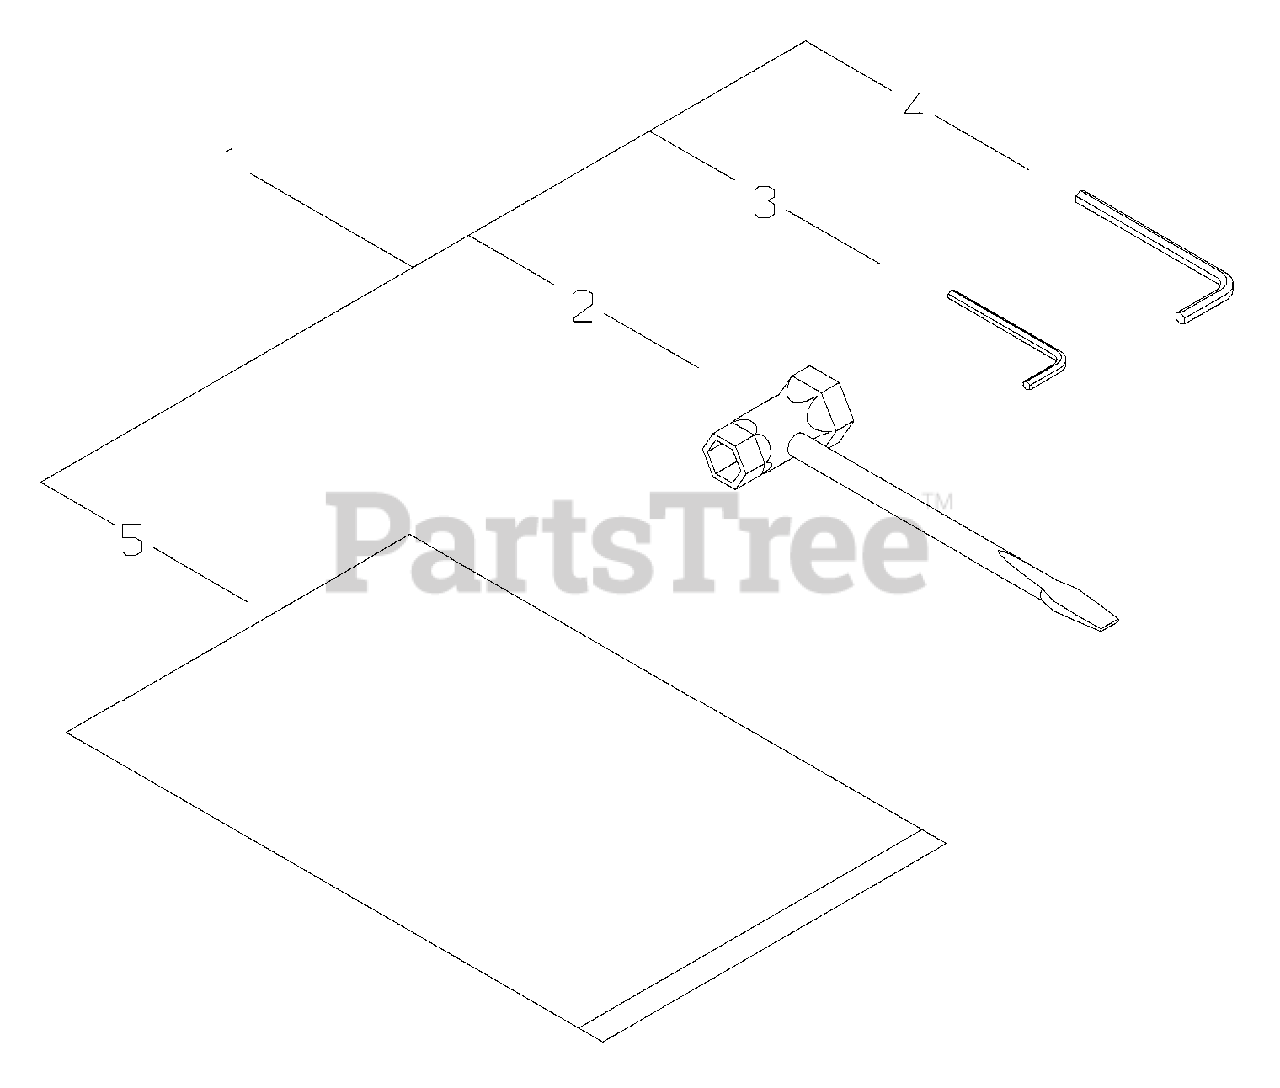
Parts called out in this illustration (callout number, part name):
1	TOOL KIT
2	T-WRENCH - 13X19mm
3	HEX KEY - 3mm
